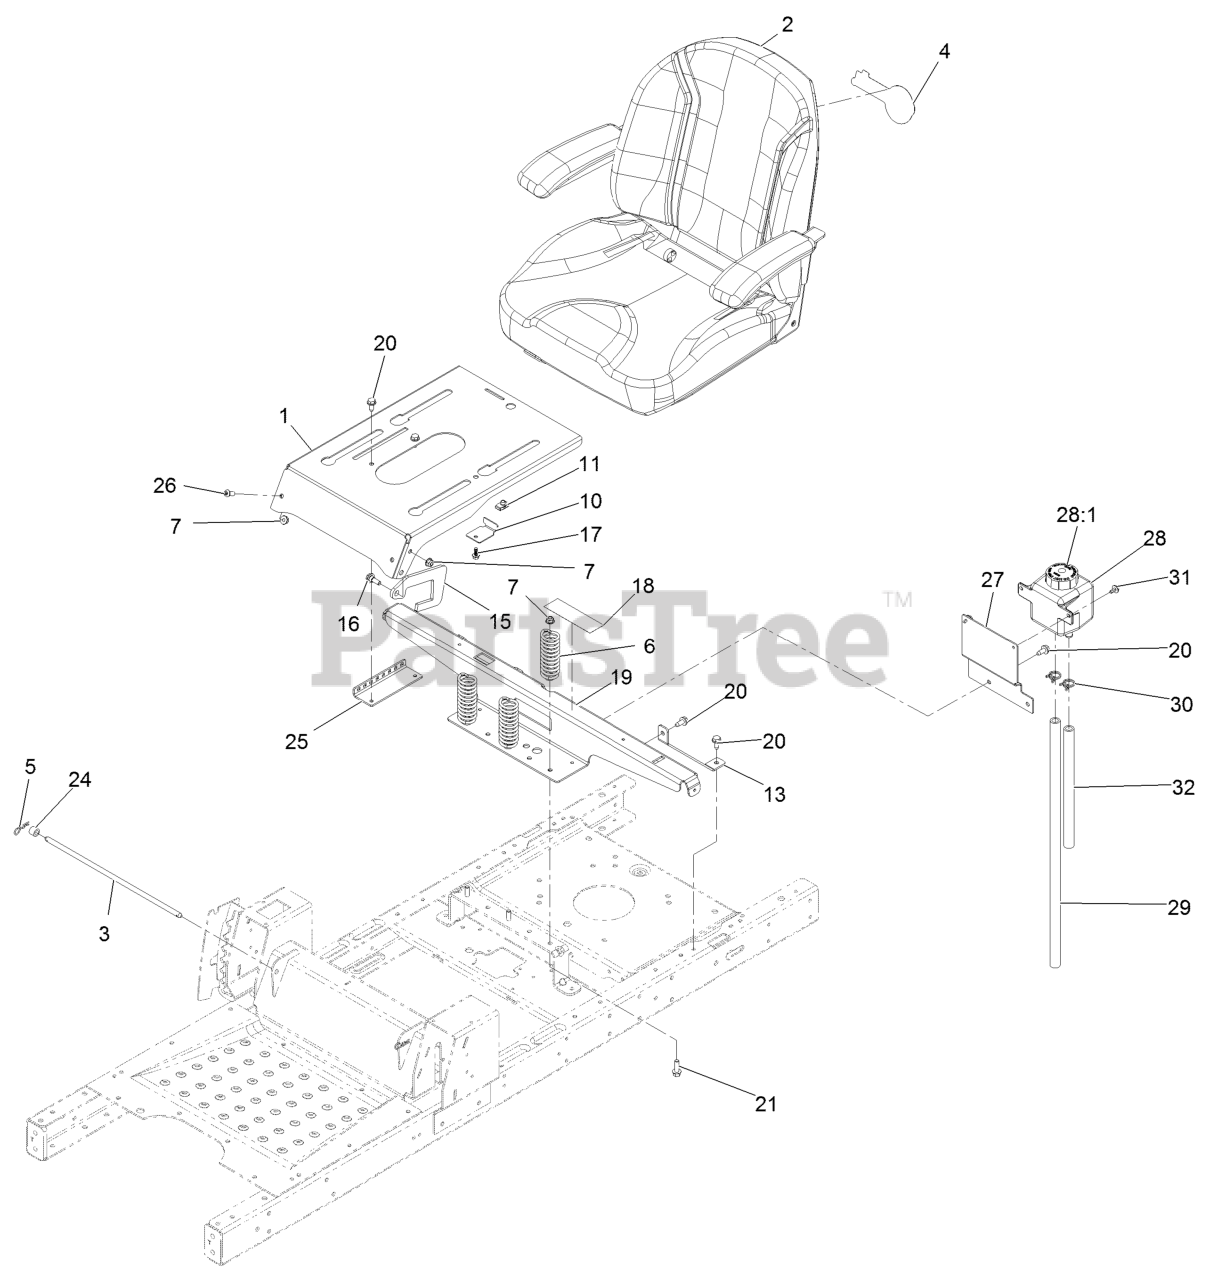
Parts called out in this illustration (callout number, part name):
2	SEAT ASM, EXMARK
3	ROD-STOP
5	PIN-COTTER
6	SPRING-COMPRESSION
7	NUT-HF, NI
10	BRACKET-STOP, SEAT
11	Nut-Retainer-Panel 1/4-20
13	SUPPORT-TANK, REAR
15	PLATE-STOP
16	SCREW-SHOULDER
17	SCREW-HHF
18	DECAL-SERVICE, CE
19	SUPPORT-POD, WIDE
20	Screw-HWH 5/16-18 X 3/4 Tf
21	SCREW-HHF
24	BUSHING-LEVER, LIFT
25	BRACKET-LATCH, SEAT
26	SCREW-HSBH
27	MOUNT-TANK
28	TANK-HYD
28:1	CAP-RESERVOIR, HYD
29	HOSE-OVERFLOW
30	CLAMP-HOSE
31	SCREW-HHFTF
32	HOSE-OVERFLOW
